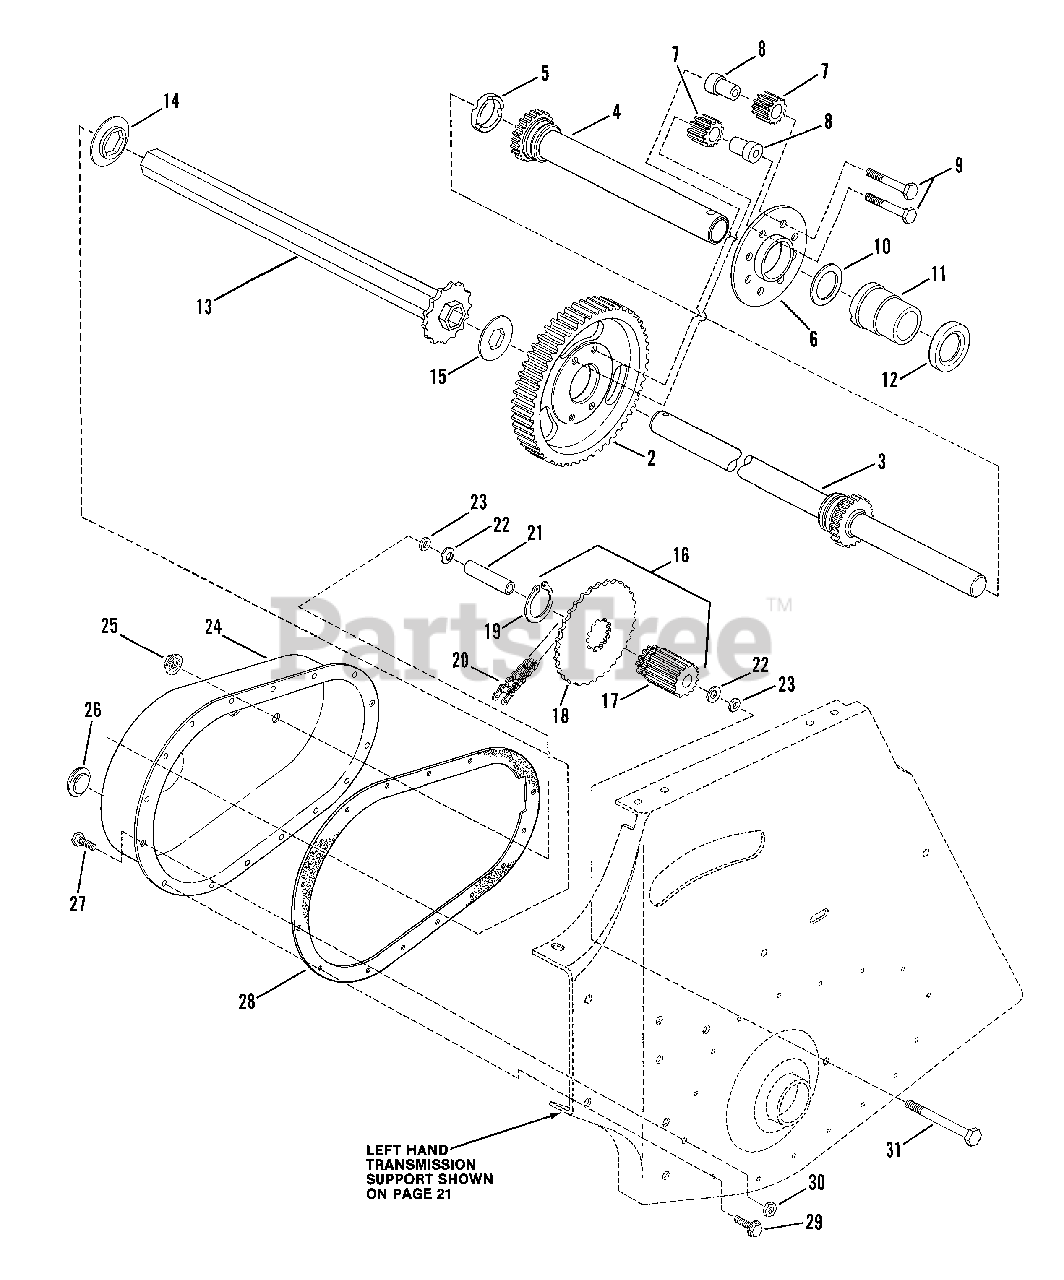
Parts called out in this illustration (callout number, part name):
2	GEAR, 63 Teeth, 10 Pitch
3	AXLE, Long
4	AXLE, Short
5	SPACER, Differential (1.25" ID x .425 Wide)
6	PLATE, Differential
7	PINION GEARS, Differential
8	SPACER, Pinion
9	BOLT, 5/16-24x1-518" Hex, Special Lock Cap
10	WASHER, Thrust
11	BEARING, Axle, L.H. Transmission Support
12	SEAL, Oil
13	ASSEMBLY, Drive Hex Tube
14	WASHER,Hex Insert
15	WASHER, Thrust
16	ASSEMBLY, Gear & Sprocket
17	GEAR, 11 Teeth, 10 Pitch
18	SPROCKET
19	RING, Retaining
20	CHAIN, 46 Pitch (#35)
21	SPACER
22	WASHER, Belleville
23	O-RING, 5/16"
24	CASE, Transmission
25	NUT, 5/16-24 Hex Flange Lock
26	PLUG, Oil Fill & Check
27	SCREW, 1/4-20x5/8" Hex Head Cap
28	GASKET, Transmission Case
29	SCREW, 1/4-20x5/8" Self-Tapping
30	NUT, 1/4-20 Hex Lock
31	BOLT, Idler, 5/16-24x2-5/8"
